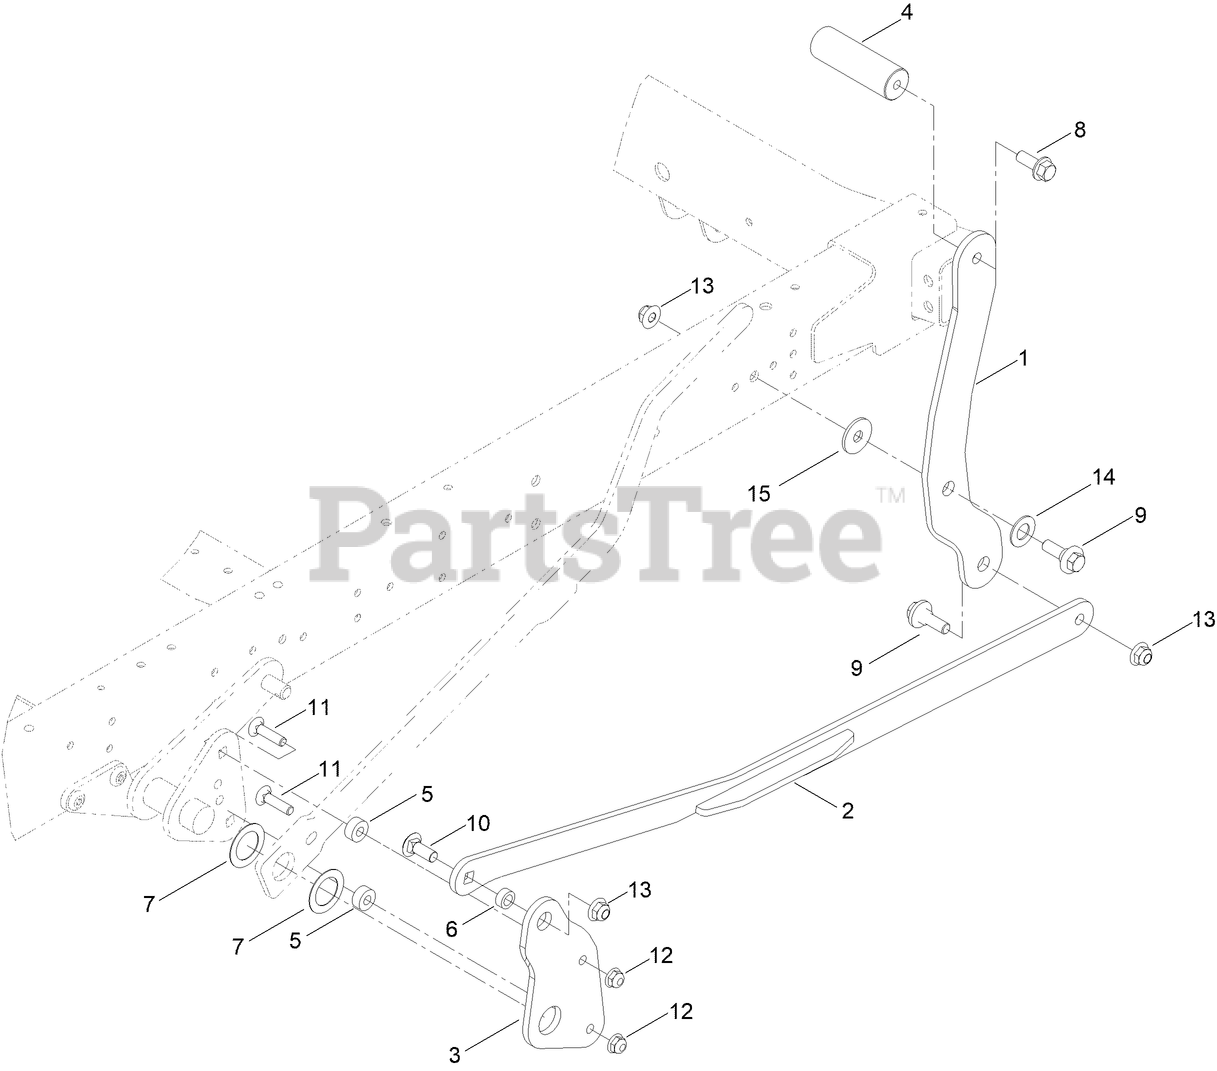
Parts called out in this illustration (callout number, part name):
1	PEDAL-LIFT
2	LINK ASM
3	PLATE-FOOTLIFT
4	PEDAL-FOOT LIFT
5	SPACER
6	SPACER
7	WASHER-THRUST
8	SCREW-HHF
9	SCREW-SHOULDER
11	BOLT-CARRIAGE
12	NUT-HF
13	NUT-HF, NI
14	WASHER-NYLON
15	WASHER-HARDENED, CZ
